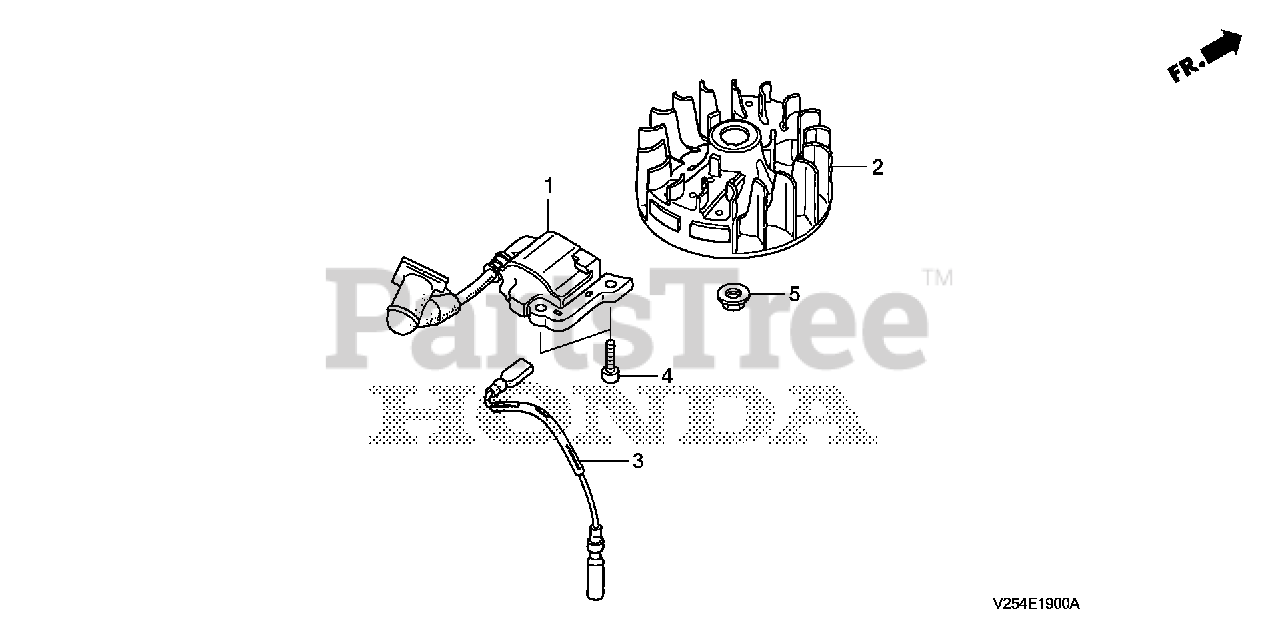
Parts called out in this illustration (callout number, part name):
1	COIL ASSY., IGNITION
2	FLYWHEEL
3	WIRE, STOP SWITCH
4	BOLT, SOCKET (4X14)
5	NUT, FLANGE (7MM)
